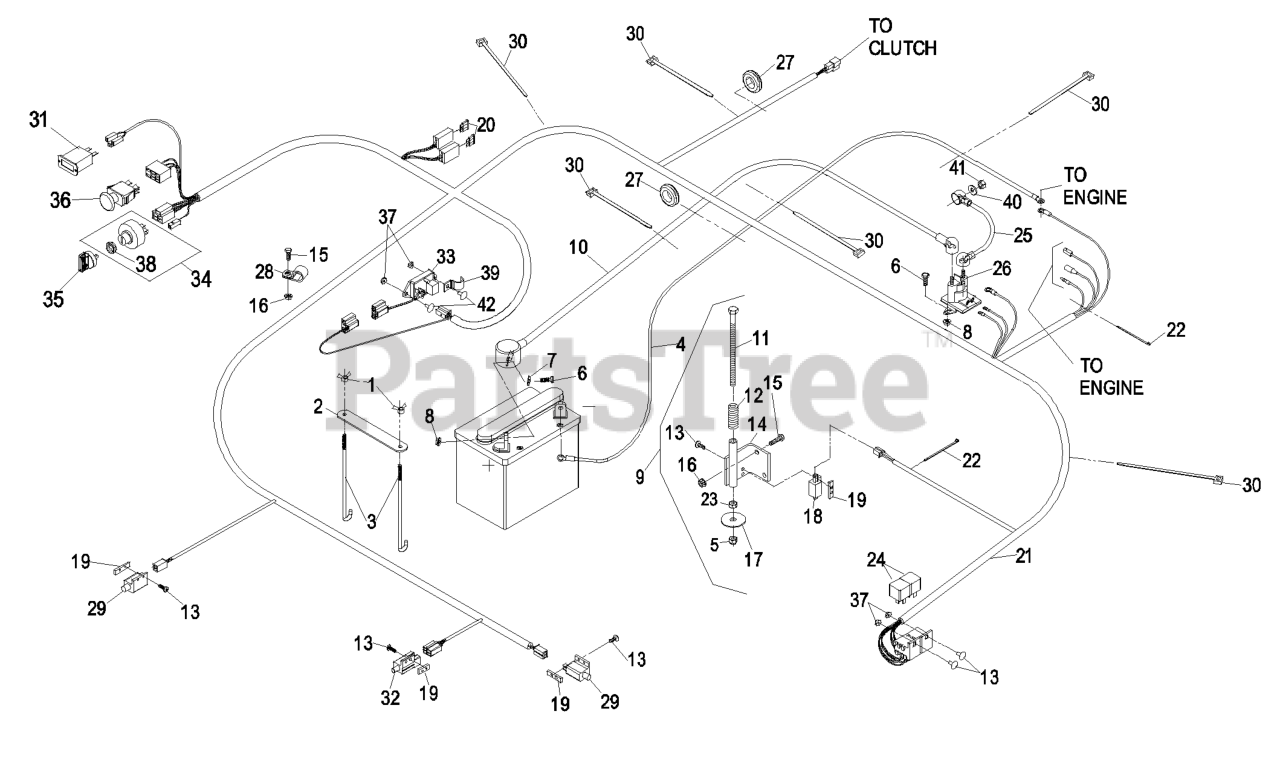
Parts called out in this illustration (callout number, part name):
1	WINGNUT
2	STRAP-HOLDDOWN, BATTERY
3	BOLT-HOLDDOWN
4	CABLE-GROUND, NEGATIVE
5	NUT-LOCK, NI
6	SCREW-HH
7	WASHER-FLAT
9	ASM,SEAT SWITCH ACTUATOR
10	POSITIVE BATTERY CABLE AS
11	SCREW-HH
12	SPRING-SWITCH, SEAT
13	SCREW-PPH
14	BRACKET-SWITCH, SEAT
15	SCREW-HH
18	SWITCH-CLOSED, NORMALLY
19	PLATE-TAPPED
20	FUSE-BLADE TYPE, 20 AMP
21	HARNESS,WIRE LCT BV
22	TIE-CABLE
23	NUT-HEX
25	POSITIVE STARTER CABLE AS
27	GROMMET
28	CLIP-LOOM
29	SWITCH-OPEN, NORMALLY
30	TIE-PLASTIC
31	METER-HOUR
33	MODULE-DELAY, SEAT
34	ASM,SWITCH W/NUT
35	KEY-IGNITION
36	SWITCH-PTO
37	NUT-LOCK, NI
38	NUT-SWITCH, IGNITION
39	CLIP-HALF, LOOM
40	WASHER-LOCK
41	NUT-HEX
42	SCREW-HEAD, TRUSS
